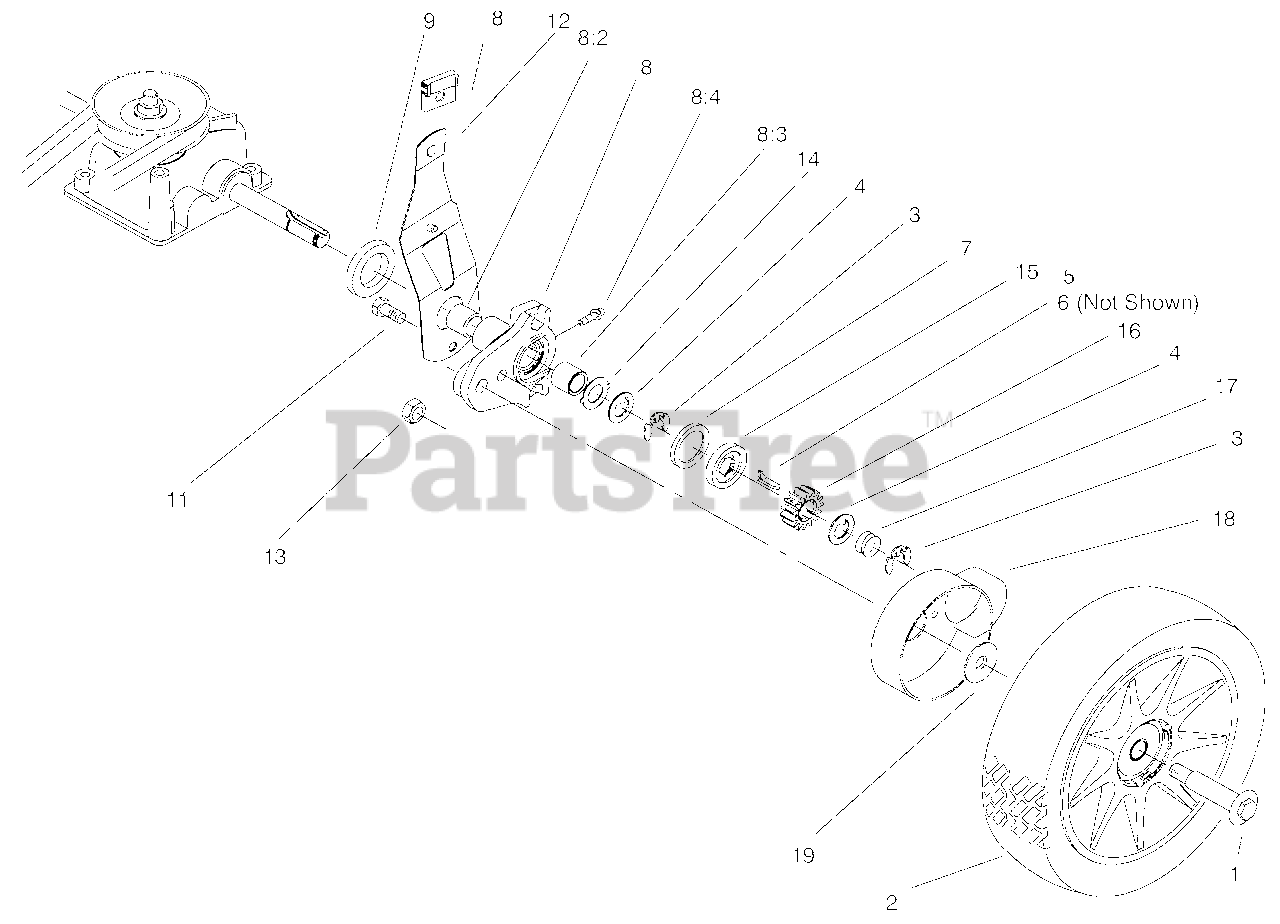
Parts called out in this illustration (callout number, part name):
1	Bolt-Shoulder
3	Ring-Retaining
4	Washer-Thrust
5	Key-Rocking LH
6	Key-Locking RH
7	Ring-Friction
8	ASM-Hgt Adj Arm
8:4	Fitting-Grease
9	Spacer-Axle Shaft
12	ASM-Spring Arm
13	Nut-Lock
14	Washer-Thrust
16	Gear-Pinion
17	Spring-Compression
18	Cover-Wheel
19	Washer-Stepped
